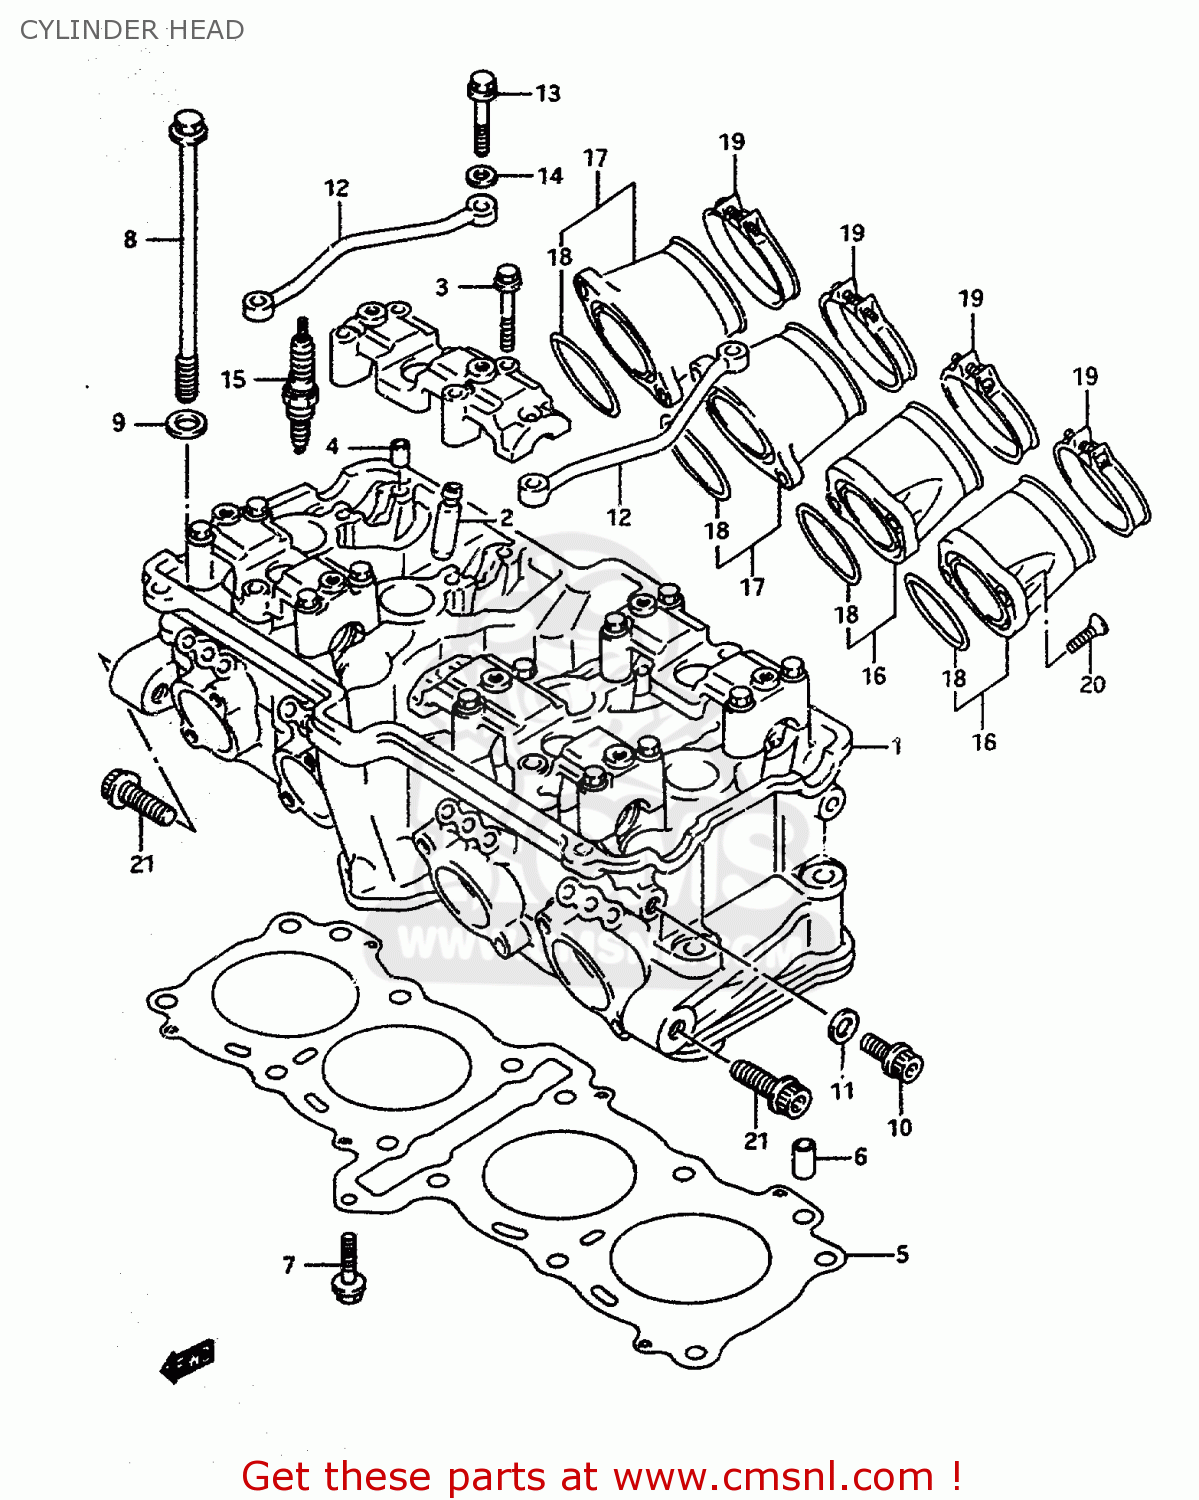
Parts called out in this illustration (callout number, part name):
1	HEAD ASSEMBLY,CYLINDER
2	GUIDE,VALVE
3	BOLT
4	PIN(6.2X8X11)
5	GASKET,CYLINDER HEAD
6	PIN
7	BOLT
8	BOLT(10X160)
9	WASHER(10.5X19X2)
10	BOLT
11	GASKET(8.2X14X1).6 (NAS)
12	PIPE,CYLINDER HEAD OIL
13	BOLT(6X39)
14	WASHER
15	PLUG,SPARK(CR8E)
16	PIPE,INTAKE NO.2
17	PIPE ASSY,INTAKE NO.2
18	O RING(D:2.4,ID:41.7)
19	CLAMP
20	SCREW
21	BOLT
